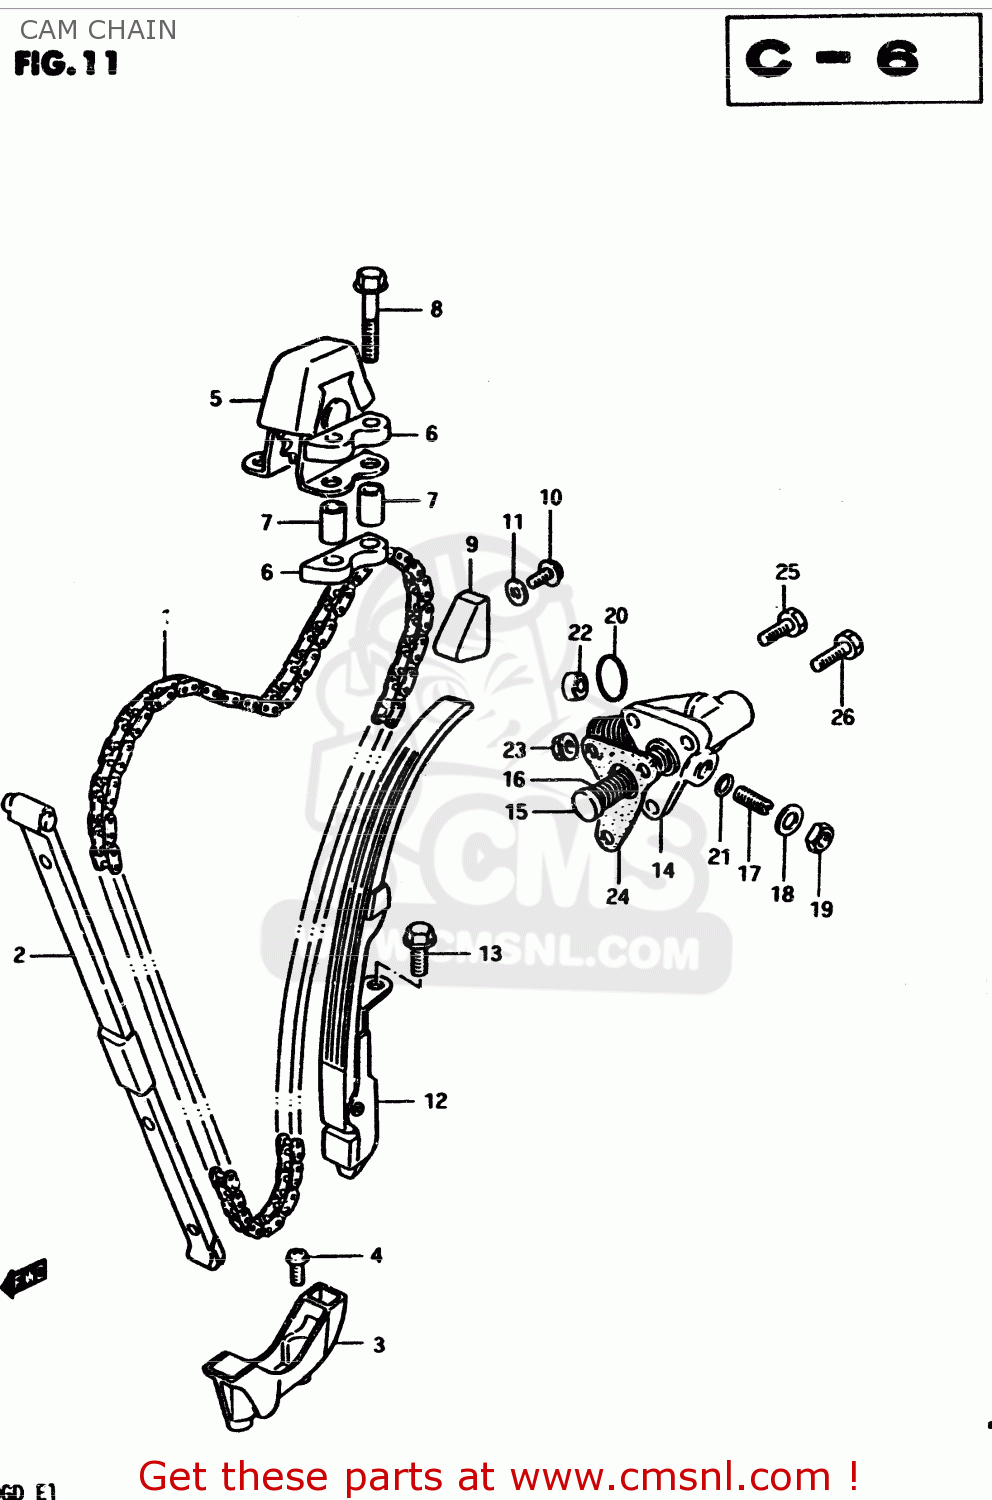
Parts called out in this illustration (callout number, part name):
1	CHAIN,CAMSHAFT DRIVE(120L)
2	GUIDE,CAM CHAIN NO.1
3	HOLDER,CAM CHAIN GUIDE
4	SCREW
5	IDLER,CAM CHAIN
6	CUSHION,IDLER
7	SPACER
8	BOLT
9	GUIDE,CAM CHAIN
10	BOLT
11	GASKET (NAS)
12	TENSIONER,CAM CHAIN
13	BOLT
14	ADJUSTER ASSY,TENSIONER
15	ROD,PUSH
16	SPRING
17	SCREW
18	WASHER
19	NUT
20	O-RING
21	O-RING
22	OIL SEAL
23	NUT
24	GASKET,TENSIONER ADJUSTER (MCA)
25	SCREW
26	SCREW
